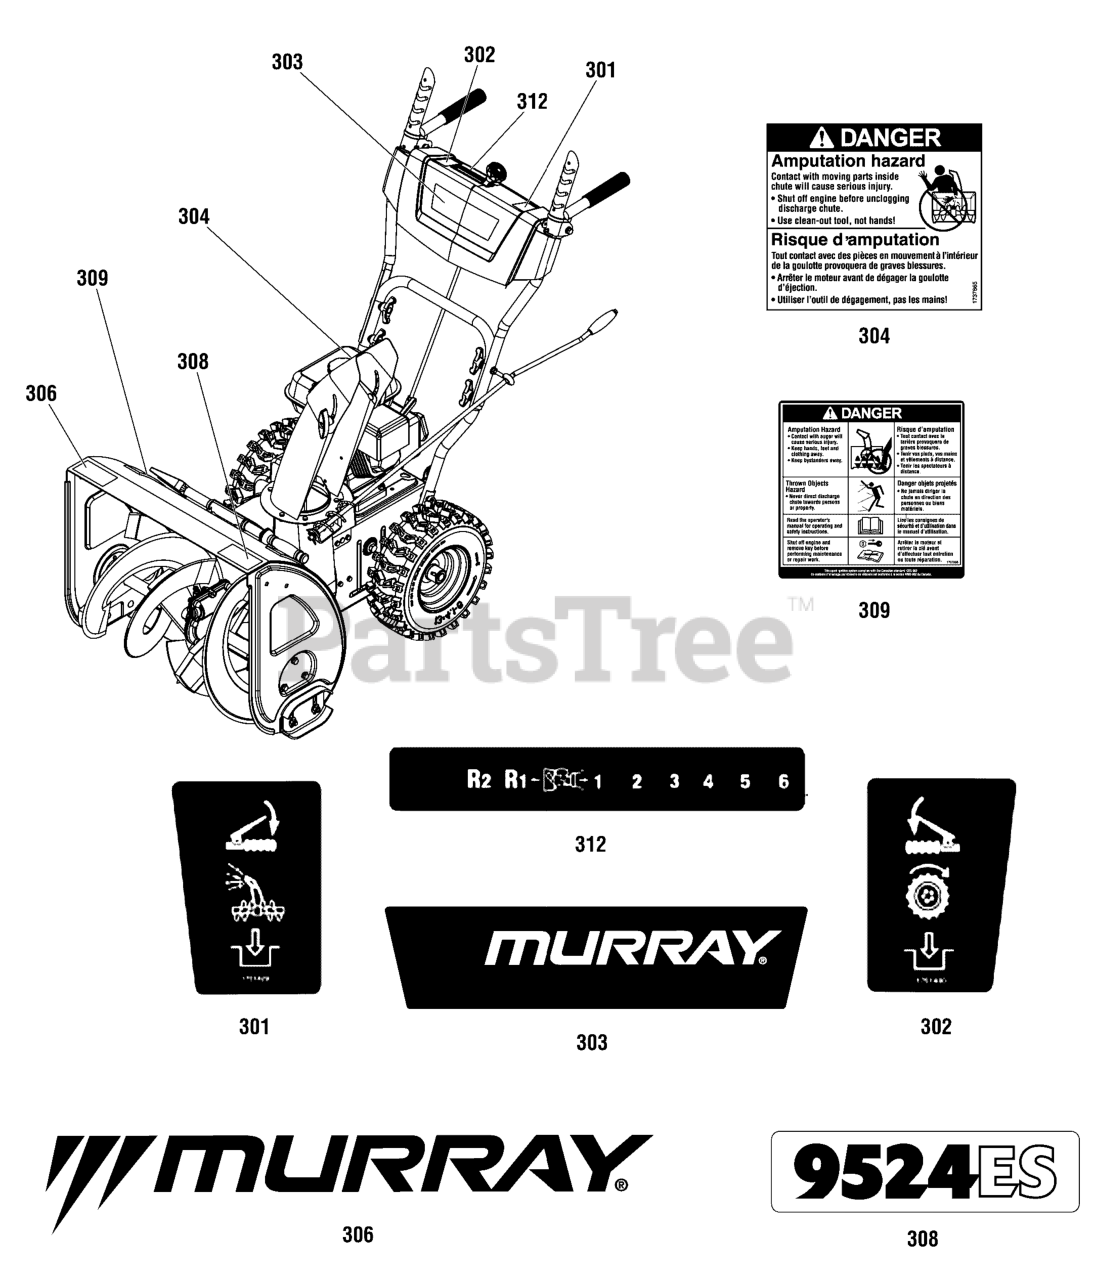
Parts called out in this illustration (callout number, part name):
1	KIT-DECAL, Murray 9524ES
301	*DECAL, Auger Control
302	*DECAL, Traction Control
303	*DECAL, Control Panel, Murray
304	DECAL, Danger Chute
306	*DECAL, Front Shroud, Murray Logo
309	DECAL, Danger Foot
312	*DECAL, 1-6 Transmission Speed Control
